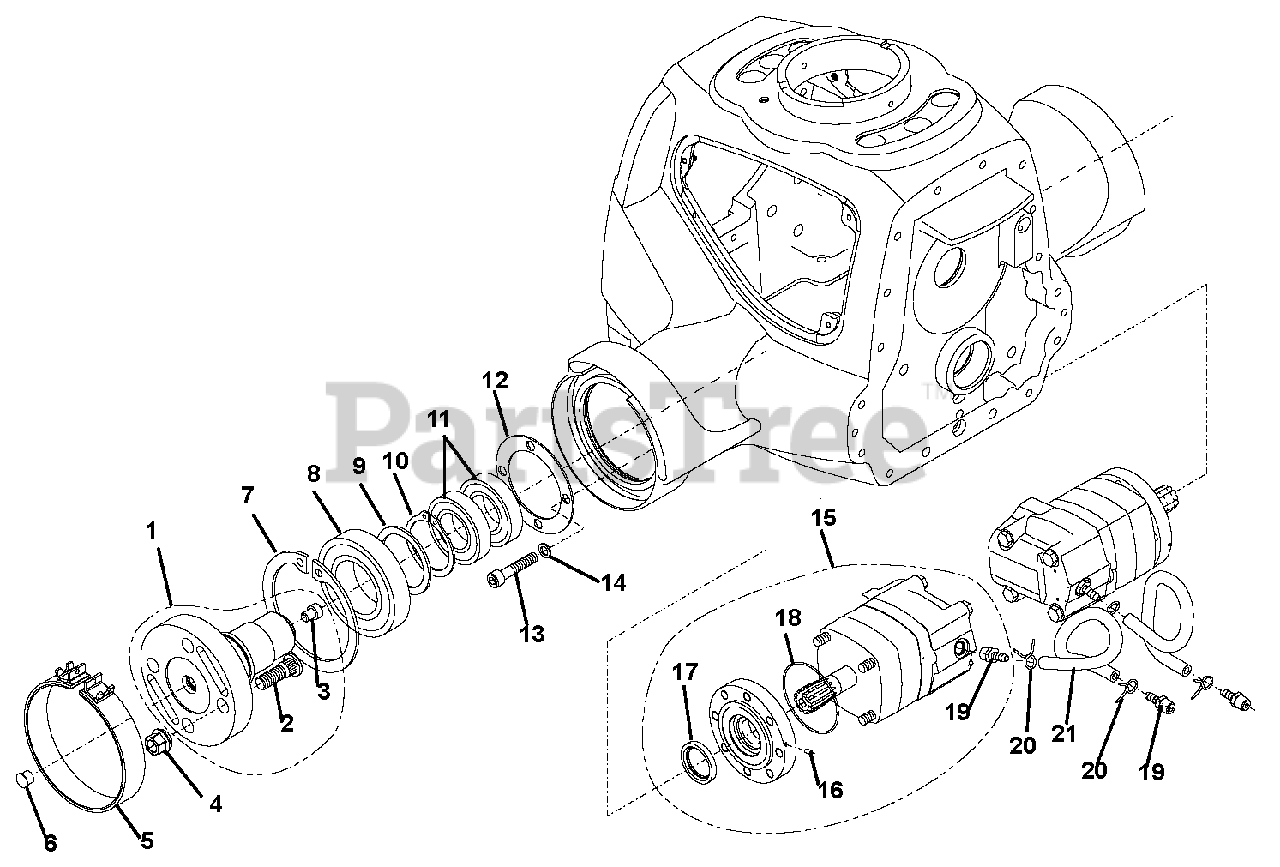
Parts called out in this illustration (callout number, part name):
1	Flange Wheel CPL (Includes 2 and 3)
4	Nut, M14 x 1.5
5	Brake Band
6	Plug, N559 TL-4-133
7	Circlip, D472 110 4.00
8	Bearing, Ball 6212 2RS
9	Washer, D988 60 x 75 x 3
10	Circlip, D471 60 2.00
11	Bearing, Ball 6009 2RS
13	Screw, D912 M10 x 50
14	Washer, FORM Z 10.2/16.1 x 1.6
15	Motor, Hydraulic (Includes 16 - 19)
16	Pin, Threaded D914 M4 x 10
17	Seal, Oil 32 x 45 x 6
18	O-Ring, 75.95 x 1.78
19	Connection, 1/4" 8 x 19
20	Hose, Clamp
